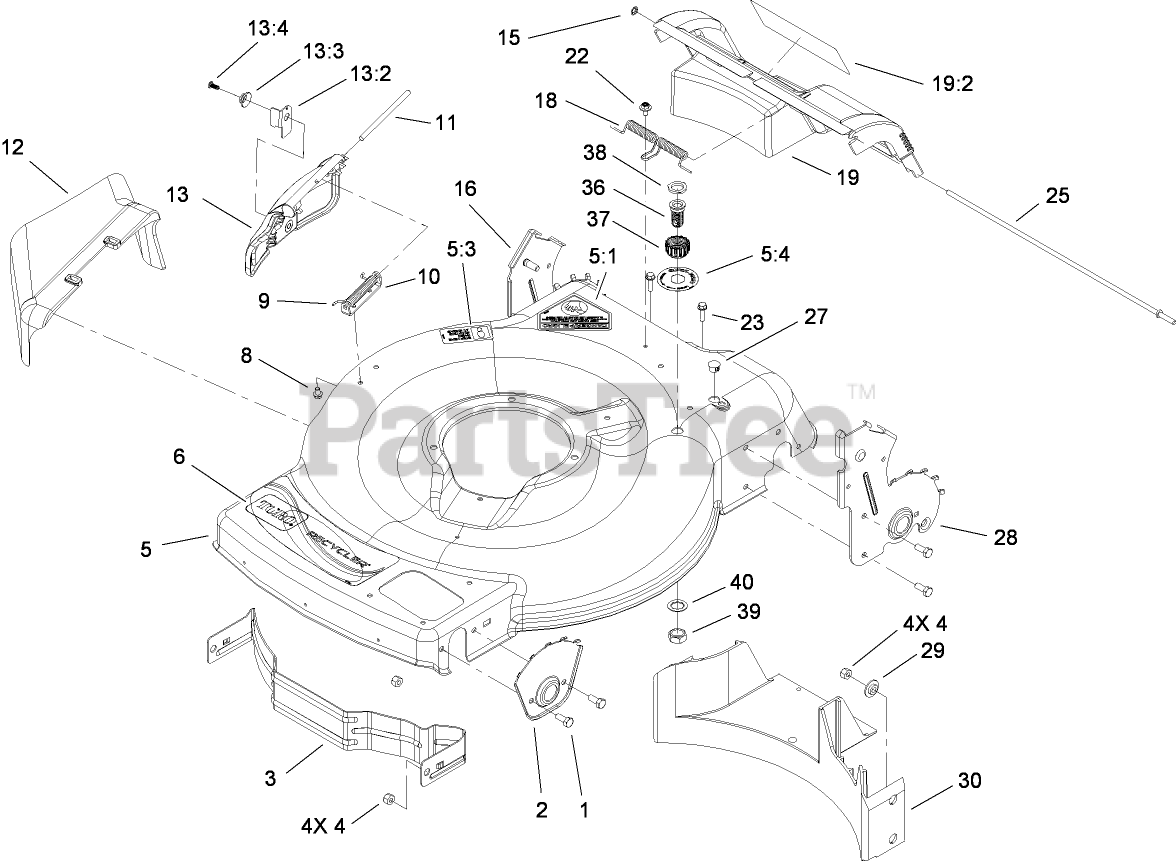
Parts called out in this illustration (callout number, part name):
1	SCREW-HH
3	BAFFLE-FRONT
4	NUT-LOCK, NI
5	BBC HOUSING ASM
5:1	DECAL-DANGER
5:3	DECAL-PLACEMENT, FOOT
5:4	DECAL-PORT, WASHOUT
6	DECAL-RECYCLER (RWD)
8	SCREW-HWH
9	SPRING-TORSION
10	BRACKET-COVER
12	CHUTE-DISCHARGE, SIDE
13	DISCHARGE DOOR ASM
13:2	LATCH-DOOR
13:3	CAP-DOOR
13:4	SCREW-PLASTITE
15	NUT-PUSH
16	8 INCH RH HOC PLATE ASM
18	SPRING-DOOR, REAR
19	REAR DOOR ASM
19:2	DECAL-WARNING
22	SCREW AND WASHER ASM
23	SCREW-HWH
25	ROD-PIVOT, REAR DOOR
27	PLUG-DOME
28	8 INCH LH HOC PLATE ASM
29	WASHER-STEPPED
30	BAFFLE-REAR
36	PORT-WASHOUT
37	COUPLING-HOSE, WASHOUT PORT
38	WASHER-SEAL, WASHOUT PORT
39	NUT-JAM
40	WASHER-LOCK
